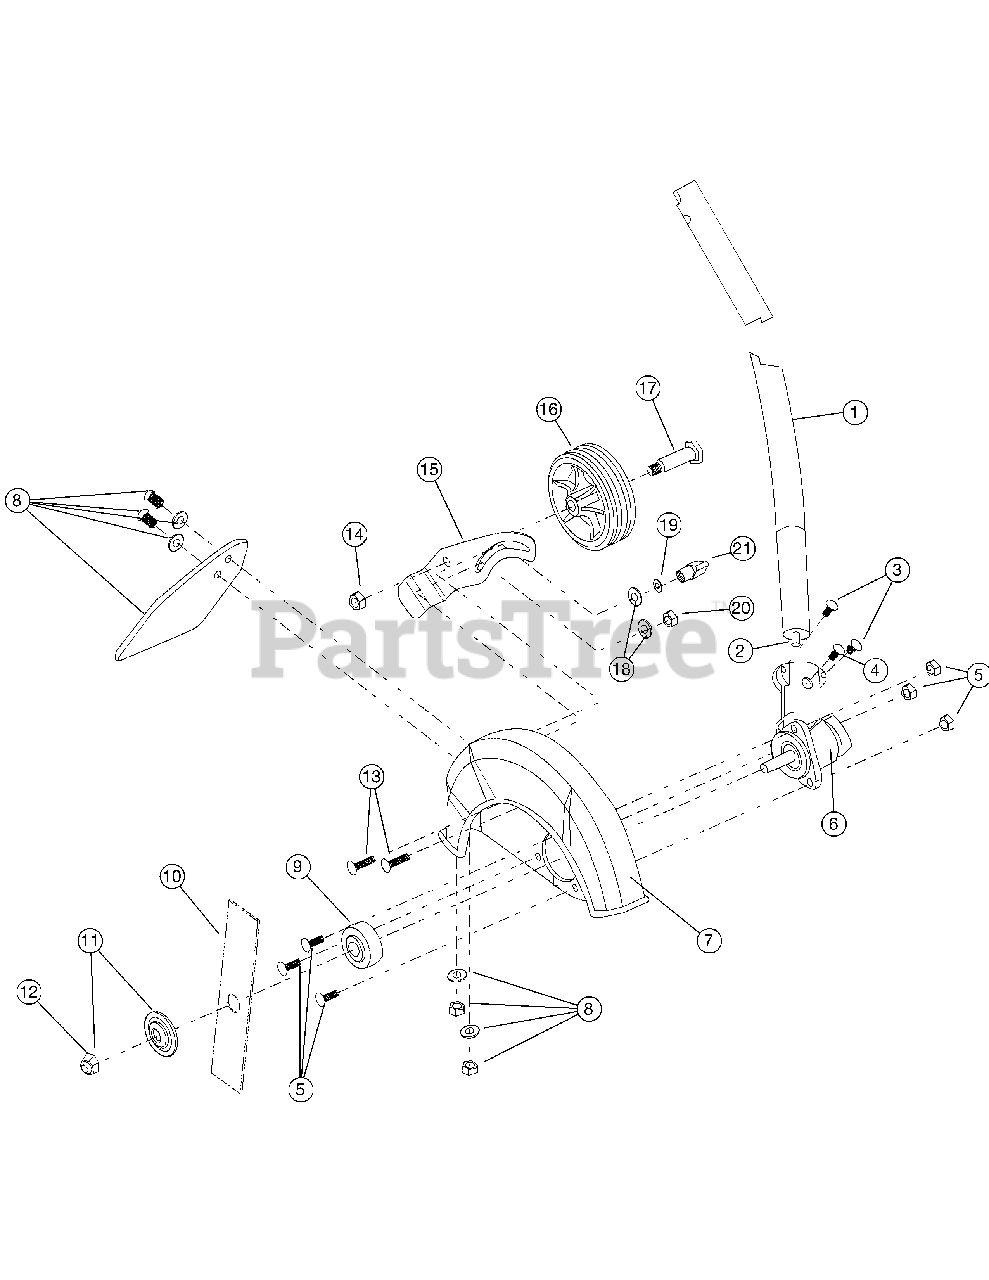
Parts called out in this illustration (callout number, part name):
1	Boom Assembly
2	Drive Shaft
3	Boom Mounting Hardware
4	Anti-Rotation Screw
5	Guard Mounting Hardware
6	Gearbox Assembly
7	Blade Guard
8	Deflector w/Hardwear
9	Spacer
10	Blade
11	Blade Clamp Washer
12	Blade Retainer Nut
13	Wheel Bracket Mounting Bolt
14	Nut
15	Edger Guide
17	Shoulder Bolt
19	Washer
20	Nut
21	Edger Guide Knob
